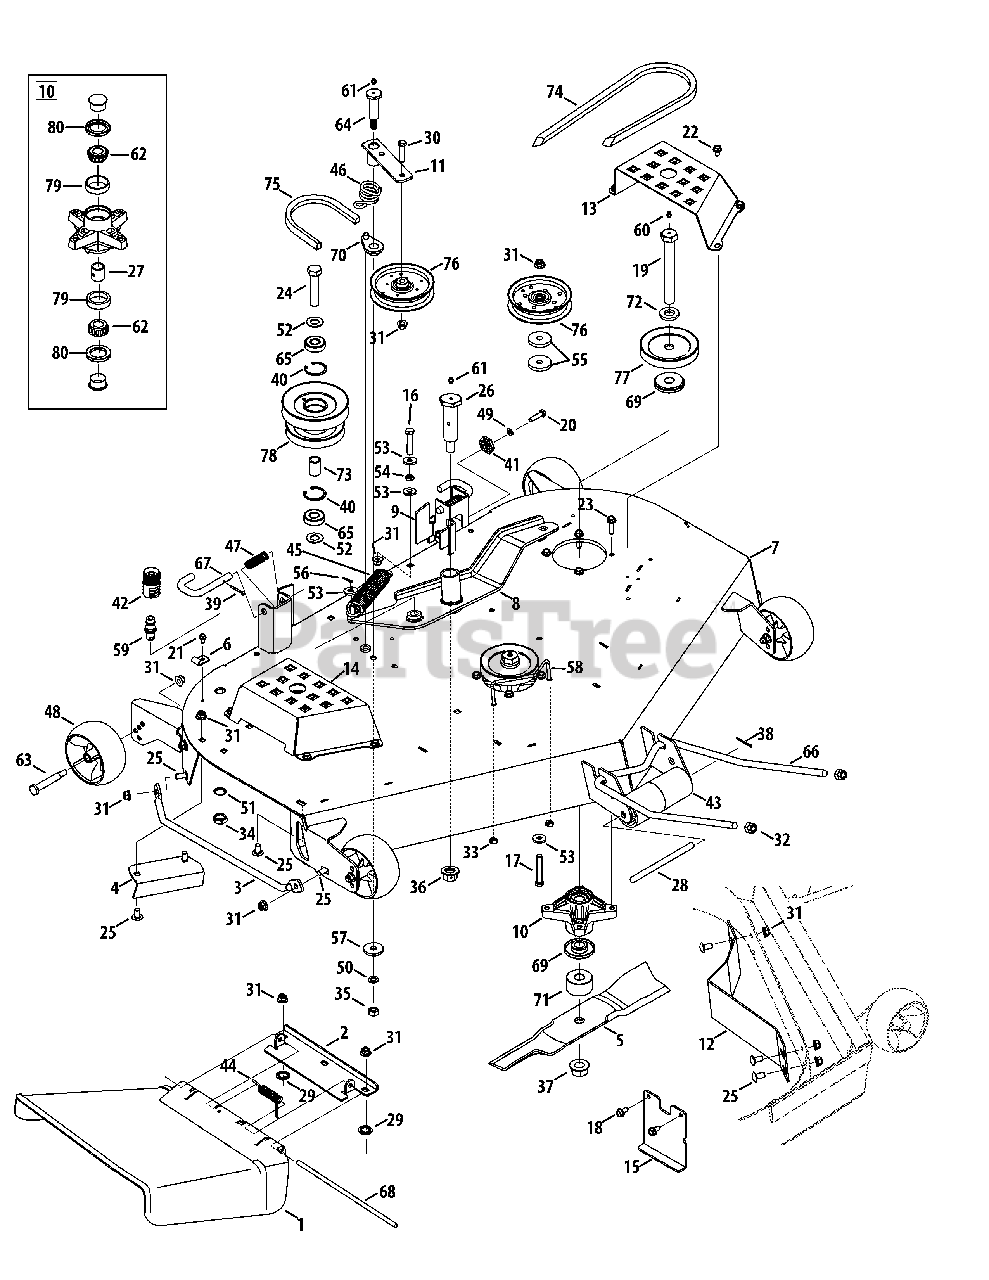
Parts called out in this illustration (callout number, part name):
1	Chute Deflector
2	Chute Bracket
3	Finger Guard
4	Micro Chute Baffle
5	Blade, Hi-Lift
6	Hook Retainer Bracket
9	Hanger Adjustment Bracket
10	Spindle Assembly
15	Up-Stop Bracket
16	Hex Screw, 3/8 x 16 x 1.75
17	Hex Screw, 3/8-16 x 2.50
18	Hex Washer, 5/16-18 x .750
19	Hex Screw, 3/4-16 x 6.00
20	Hex Screw, 5/16-18 x 1.25
21	Hex Washer Screw, 1/4-20 x .500
22	Hex Washer Screw, 5/16-18 x .625
23	Hex Washer Screw, 5/16-18 x 1.50
24	Hex Screw, 5/8-18 x 3.00
25	Carriage Bolt, 3/8-16 x 1.00
26	Shoulder Screw, 1.0 x 3.00
27	Bearing Spacer, .78 x 1.0 x 1.0425
28	Roller Pin, 1/2 x 7.31
29	Push Nut, 3/8
30	Hex Screw, 3/8-16 x 1.50
31	Flange Lock Nut, 3/8-16
32	Flex Lock Nut, 1/2-13
33	Hex Lock Nut, 1/4-20
34	Hex Nut, M16-1.5
35	Hex Nut, 7/16-14
36	Flange Lock Nut, 5/8-18
37	Flange Lock Nut, 3/4-16
38	Cotter Pin, 3/32 x 1.25
39	Cotter Pin, 5/32 x 1.25
40	Retainer Ring
41	Deck Adjustment Gear
42	Water Nozzle Adapter
43	Front Roller
44	Torsion Spring, 180 x .639 x 2.16 x .12
45	Extension Spring, 1.25 x 6.9
46	Idler Torsion Spring, 1.10 x 1.3
47	Compression Spring, .66 x 1.8
48	Deck Wheel, 5.0
49	Lock Washer, 5/16
50	Lock Washer, 7/16
51	Lock Washer, 5/8
52	Flat Washer, .65 x 1.25 x .075
53	Flat Washer, .385 x 1.0 x .135
54	Jam Nut, 3/8-16
55	Flat Washer, .4375 x 1.75 x .25
56	Cotter Pin, 3/32 x .75
57	Flat Washer, .45 x 1.5 x .172
58	Belt Drive Guard
59	Deck Water Nozzle
60	Grease Fitting, 1/4-28 x 3/16
61	Drive Lube Fitting, 3/16
62	Cone Bearing, .750
63	Shoulder Screw, 1/2 x 2.50
64	Shoulder Screw, 7/16-14 x .687 x 2.443
65	Ball Bearing, .625 x 40 x 12
66	Front Hanger Rod
67	Mower Support Pin
68	Chute Deflector Rod
69	Spindle Spacer
70	Spring Retainer
71	Spindle Spacer, .760 x 2.0 x 1.10
72	Spacer, .812 x .218
73	Spacer, .88 x .635 x 1.25
76	Idler Pulley
78	Double Pulley
79	Bearing Cup, .750
